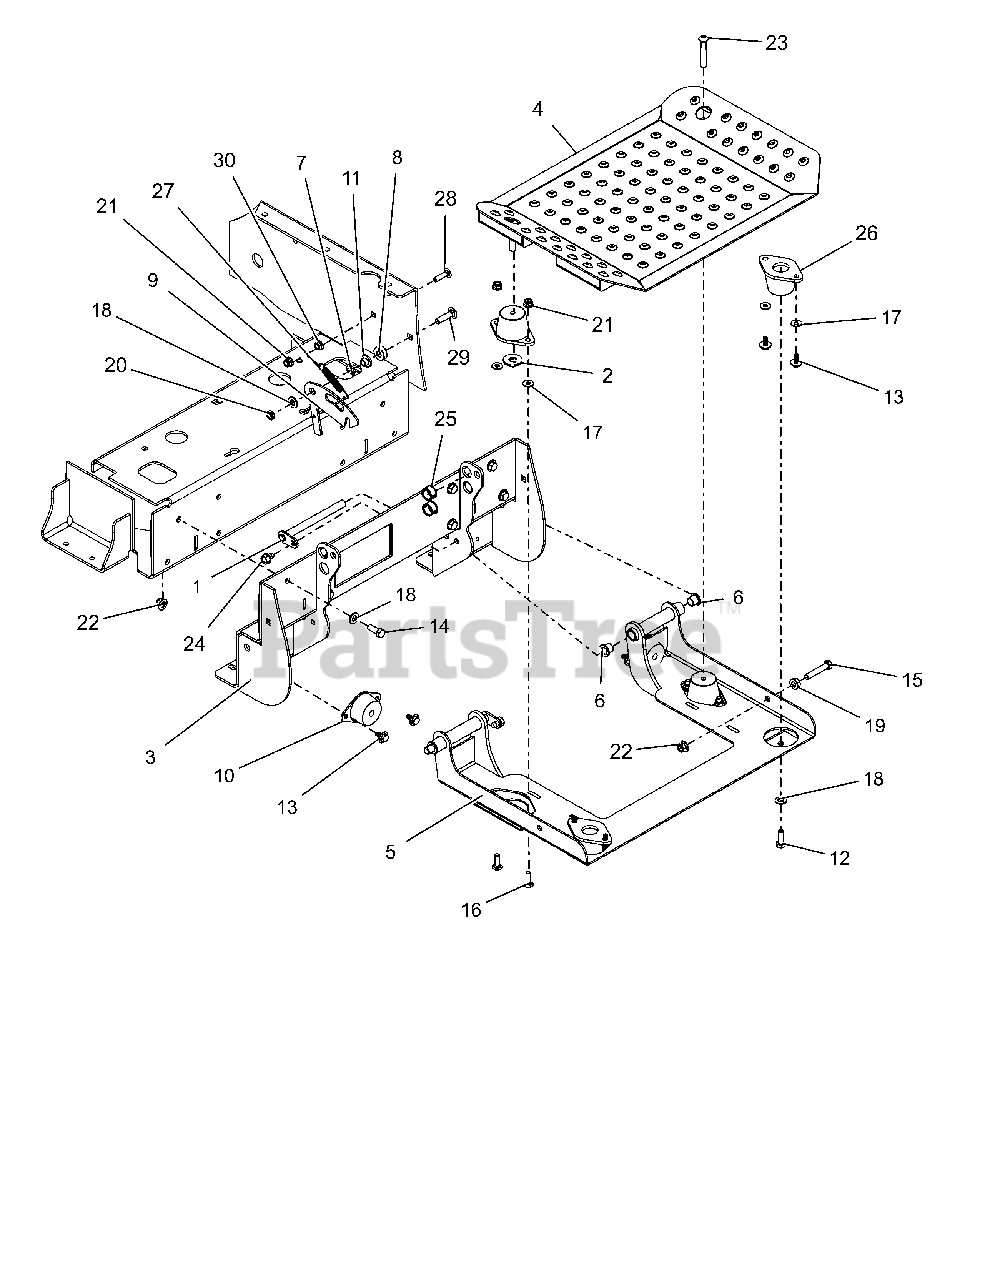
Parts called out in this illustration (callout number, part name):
1	WLDT, PIN AND LOCK Y
2	WLDMT, SEAT RETAINER
3	WLDMT, PLATFORM SUPPORT
4	WLDMT, PLATFORM TOP
5	WLDMT, PLATFORM CARRIER
6	BRG, FLG .500X.620X.500 BRNZ
7	WAVE WASHER .531X.781X.125FH
8	SPCR, .375 X 1.00 X .342
9	LATCH, PLATFORM SIDE
10	MOUNT, ENGINE, VIBRATION ISO
11	BSHG-FLG .385X.500X.875X.406
12	BLT-HEX .38-16X1.0 GR8 YZ EP30
13	BOLT, 5/16-18X.625 SLF TAP FLG
14	@BLT-HEX .38-16X1.00 GR5 YWZC
15	@BLT-HEX .38-16X2.00 GR5 YWZC
16	@BLT-RDHDSQNK .31-18X1.00 G5YZ
17	@WSHR-FL-STL.312X.734X.065 YWZ
18	@WSHR-FL-STL.406X.812X.065 YWZ
19	@NUT-SPNLK-FLG .375-16 YWZC
20	@NUT-LK-CTR-JAM .375-16 YWZC
21	@NUT-LK-NYL-FLG .31-18 YWZC
22	@NUT-LK-NYL-FLG .38-16 YWZC
23	BLT-BTHD-SOCKET .38-16X2.25FTH
24	@SCR-TAP .38-16X.50 HWH TR YWZ
25	BUSH, PANEL SNAP .687X.875X.56
26	MOUNT, ISOLATOR
27	SPRING, EXTENSION
28	@BLT-RDHDSQNK .31-18X1.25 G5YZ
29	@BLT-RDHDSQNK .38-16X1.50 G5YZ
30	@NUT-SPNLK-FLG .312-18 YWZC
